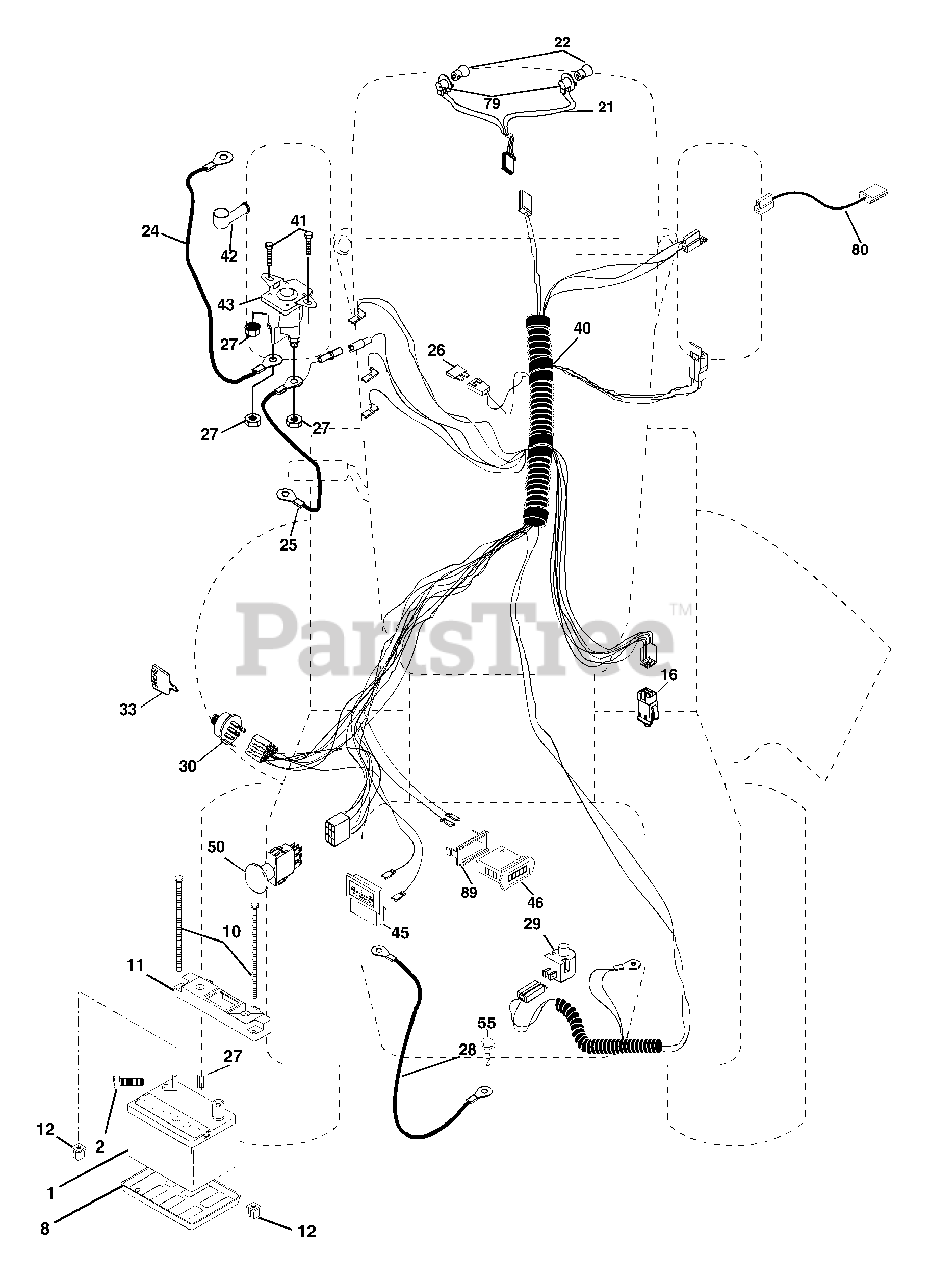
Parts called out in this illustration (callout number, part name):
1	Battery
2	Bolt, Hex 1/4-20 x 3/4
8	Tray, Battery
10	Bolt, Battery, Front 1/4-20 x 7-1/2
11	Holddown, Battery, Front
12	Nut, Push, Nylon, Battery, Front 1/4
16	Switch, Interlock
21	Harness, Light
22	Bulb Light #1156
24	Cable Starter
25	Cable
26	Fuse
27	Nut, Hex, Keps 1/4-20 unc
28	Cable, Ground
29	Switch, Seat
30	Switch, Ignition
33	Key
40	Harness, Ignition
41	Screw Thd Cut 1/4-20 x 1/2
42	Cover Terminal
43	Solinoid w/brass plunger
45	Ammeter
46	Hourmeter
50	Switch, PTO
55	Screw, Thd. Roll. 5/16-18 x 1/2
79	Socket Asm Bulb Twistlock
80	Harness Clutch EXV
89	Bracket Snap-In Hourmeter
